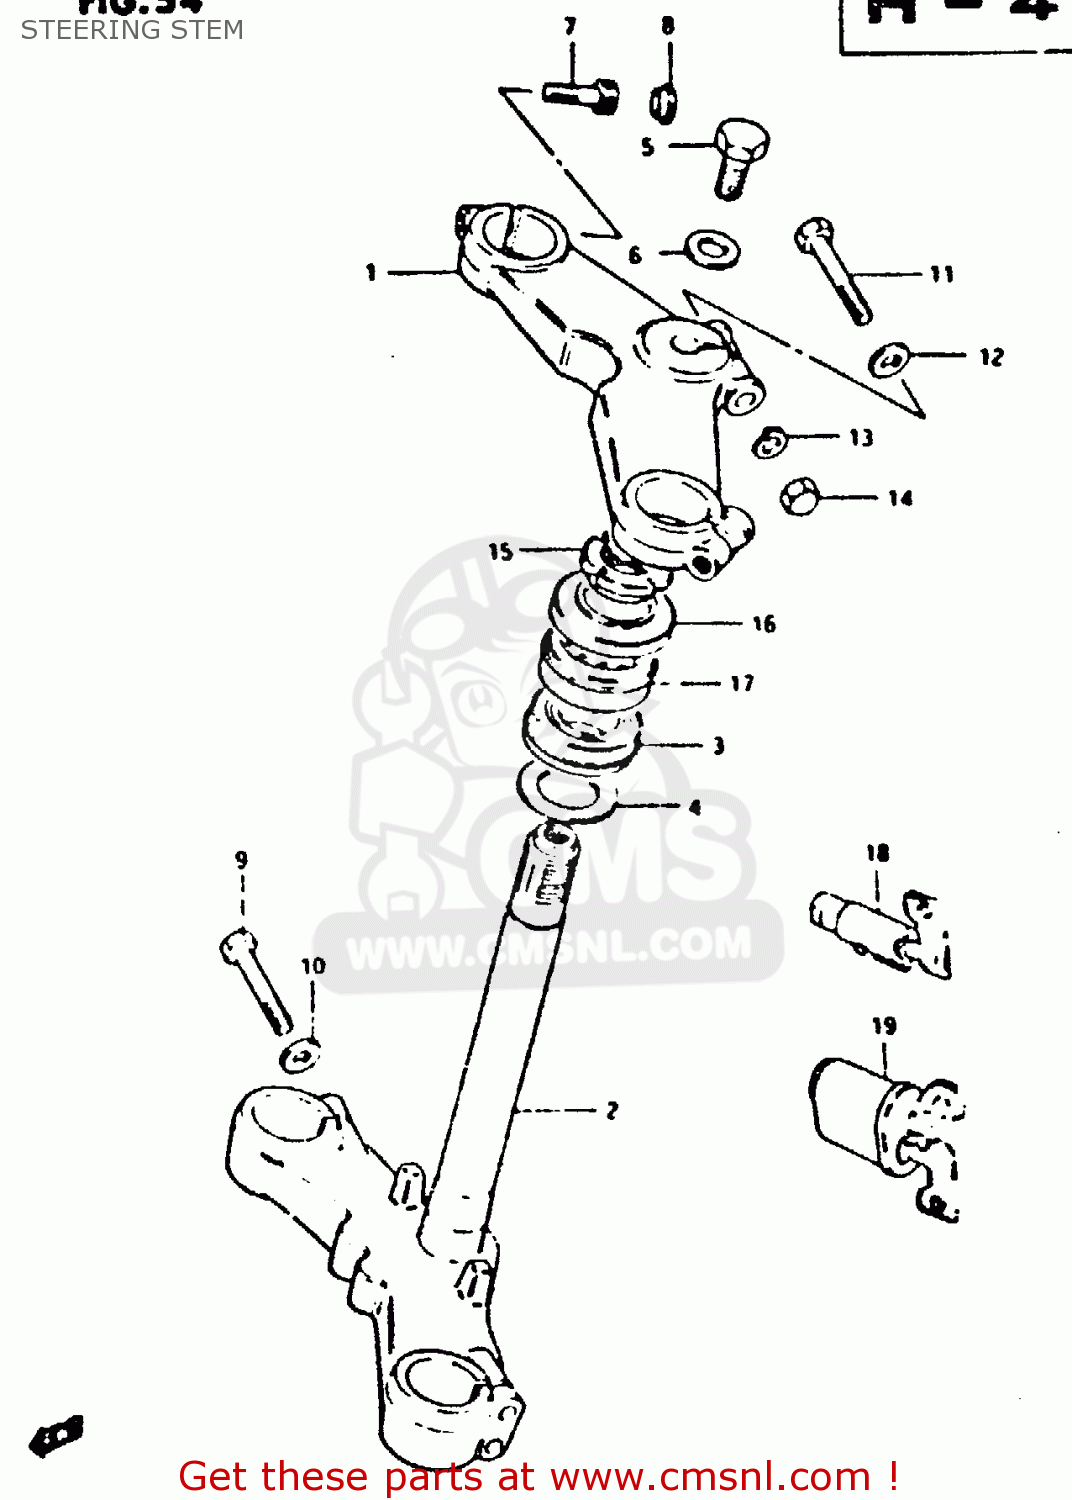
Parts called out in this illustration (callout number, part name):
1	HEAD,STEERING STEM
2	STEM,STEERING
3	BEARING
4	WASHER,THRUST
5	BOLT,STEERING STEM HEAD
6	WASHER
7	NUT,STEM HEAD
8	CAP(OD:20)
9	BOLT 8X40
10	LOCK WASHER
11	BOLT 8X50
12	WASHER
13	LOCK WASHER
14	NUT
15	NUT,STEERING STEM
16	DUST SEAL,STEERING UPR
17	TAPER,ROLLER BEARING
18	LOCK ASSEMBLY,STEERING (NEI
19	LOCK ASSY, STEERING (NEIMAN TYPE EXECUTE
